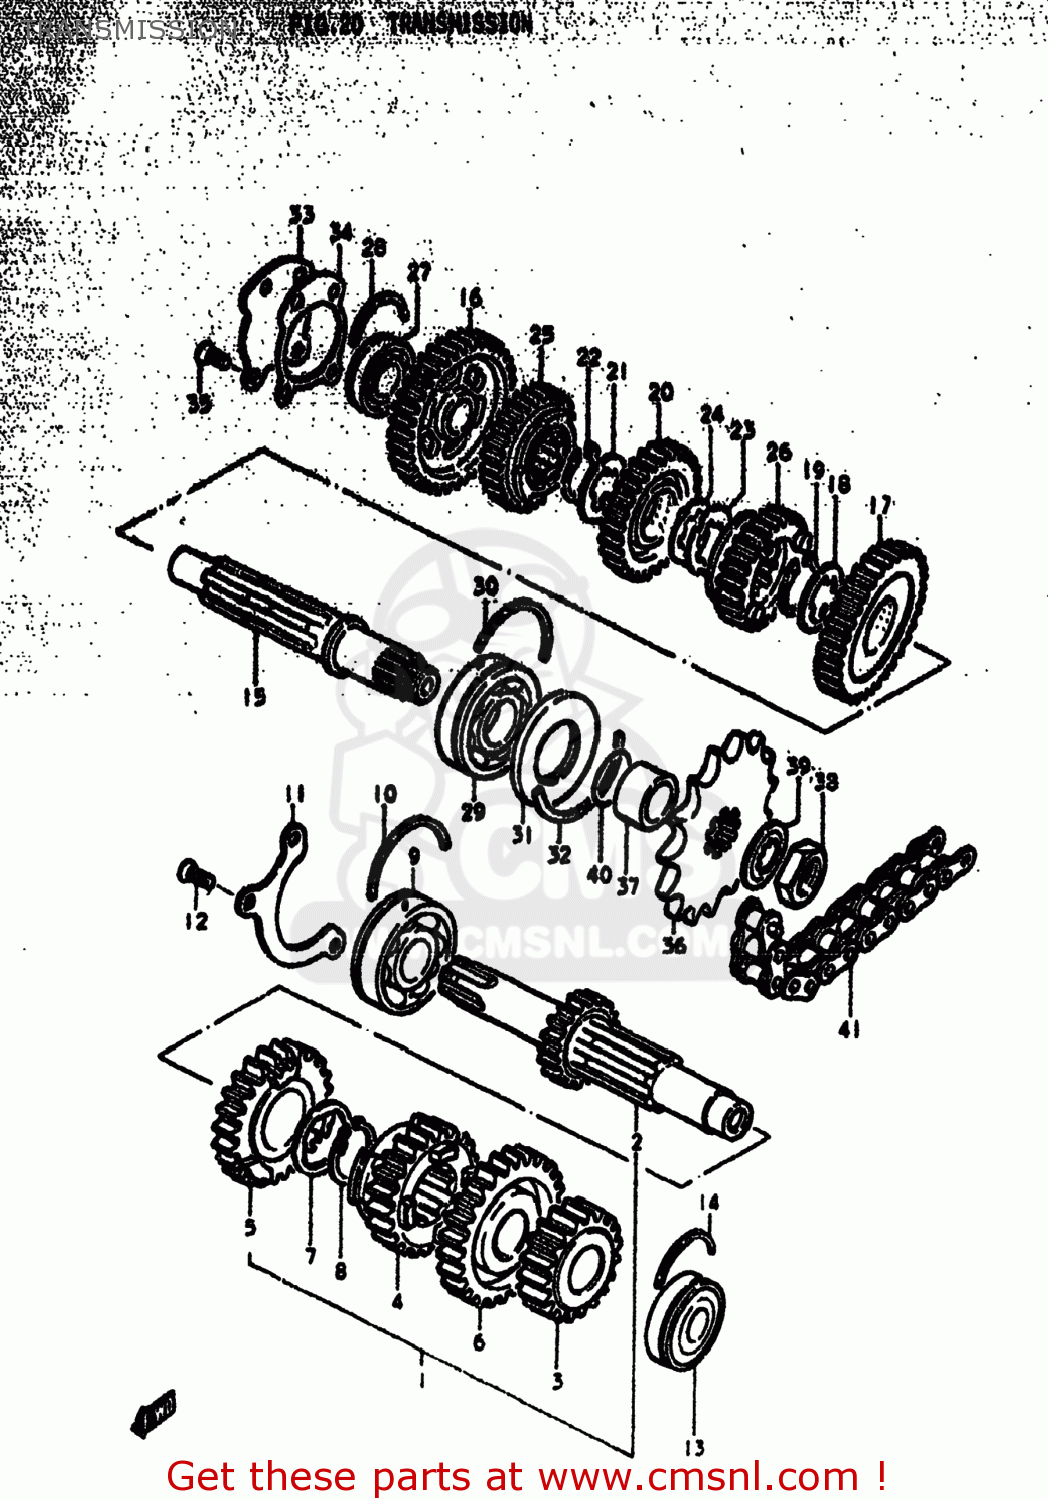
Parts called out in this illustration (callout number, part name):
1	SHAFT,COUNTER
2	SHAFT,COUNTER
3	GEAR,SECOND DRIVE
4	GEAR,THIRD DRIVE (NT:21)
5	GEAR,FOURTH DRIVE
6	GEAR,FIFTH DRIVE
7	WASHER,LOCK
8	CIRCLIP
9	BEARING(25X62X17)
10	C-RING
11	RETAINER,CNTR SHAFT BEARING
12	SCREW
13	BEARING(20X47X14)
14	C RING
15	SHAFT,DRIVE
16	GEAR,FIRST DRIVEN
17	GEAR,SECOND DRIVEN
18	WASHER,LOCK
19	CIRCLIP
20	GEAR,THIRD DRIVEN (NT:29)
21	WASHER,LOCK
22	CIRCLIP
23	WASHER,LOCK
24	WASHER
25	GEAR,FOURTH DRIVEN
26	GEAR,FIFTH DRIVEN
27	BEARING
28	C RING
29	BEARING(25X62X17)
30	C-RING
31	SEAL,OIL(32X62X7)
32	C RING
33	PLATE,DRIVE SHAFT
34	GASKET,DRIVESHAFT PLATE (MCA)
35	SCREW
36	SPROCKET,ENGINE (NT:15)
37	SPACER(25X32X18.6)
38	NUT
39	WASHER
40	O RING(D:1,ID:24.5)
41	CHAIN ASSEMBLY,DRIVE
